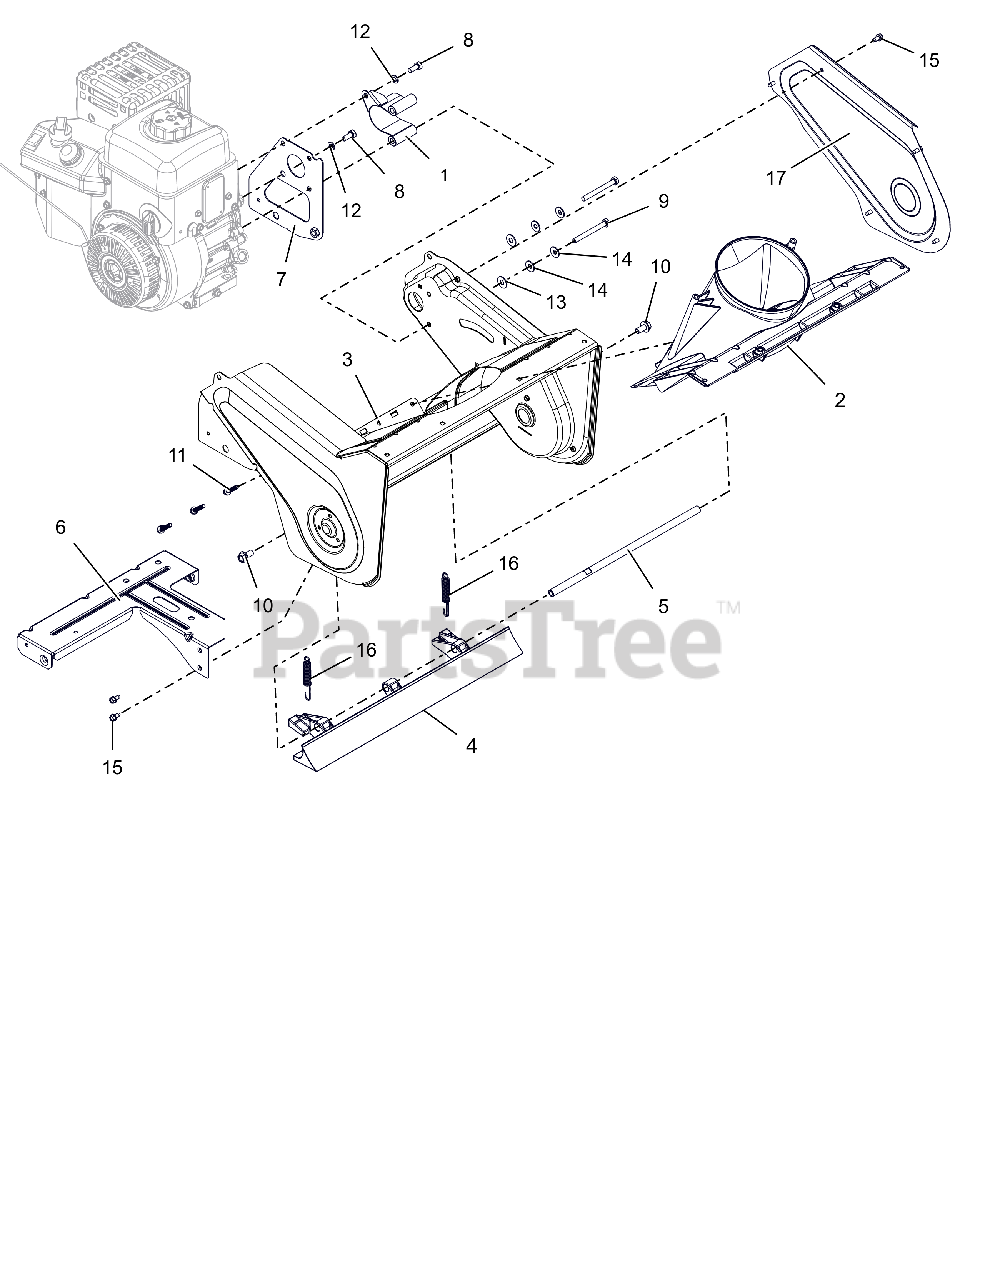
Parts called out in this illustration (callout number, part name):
1	FRAME, SPCR PTO
2	NECK, DISCHARGE
3	WLDMT, HOUSING - CSS
4	BLADE, SCRAPER - PIVOTING
5	ROD, PIVOT - SCRAPER
6	FRAME, ENGINE T-PLATE
7	FRAME, DRIVE BRACKET - WLMT
8	BLT-HEX .31-24X.75 GR5YZ EP30
9	@BLT-HEX .31-24X3.00 GR5 YWZC
10	BLT-SERHFWH .38-16X.75 YWZC
11	SCR-TAP .25-10X1.25 HWH YWZC
12	@WSHR-LK .31X.078 REG YWZC
13	WSHR-HDND .375X.875X.064 YWZC
14	WSHR,BLVL-.322X.813X.063
15	SCR-TAP .25-20X.50 HWH TR YWZ
16	SPRING,EXT-.063 X .500 X 3.500
17	COVER, BELT DRIVE - HOUSING
